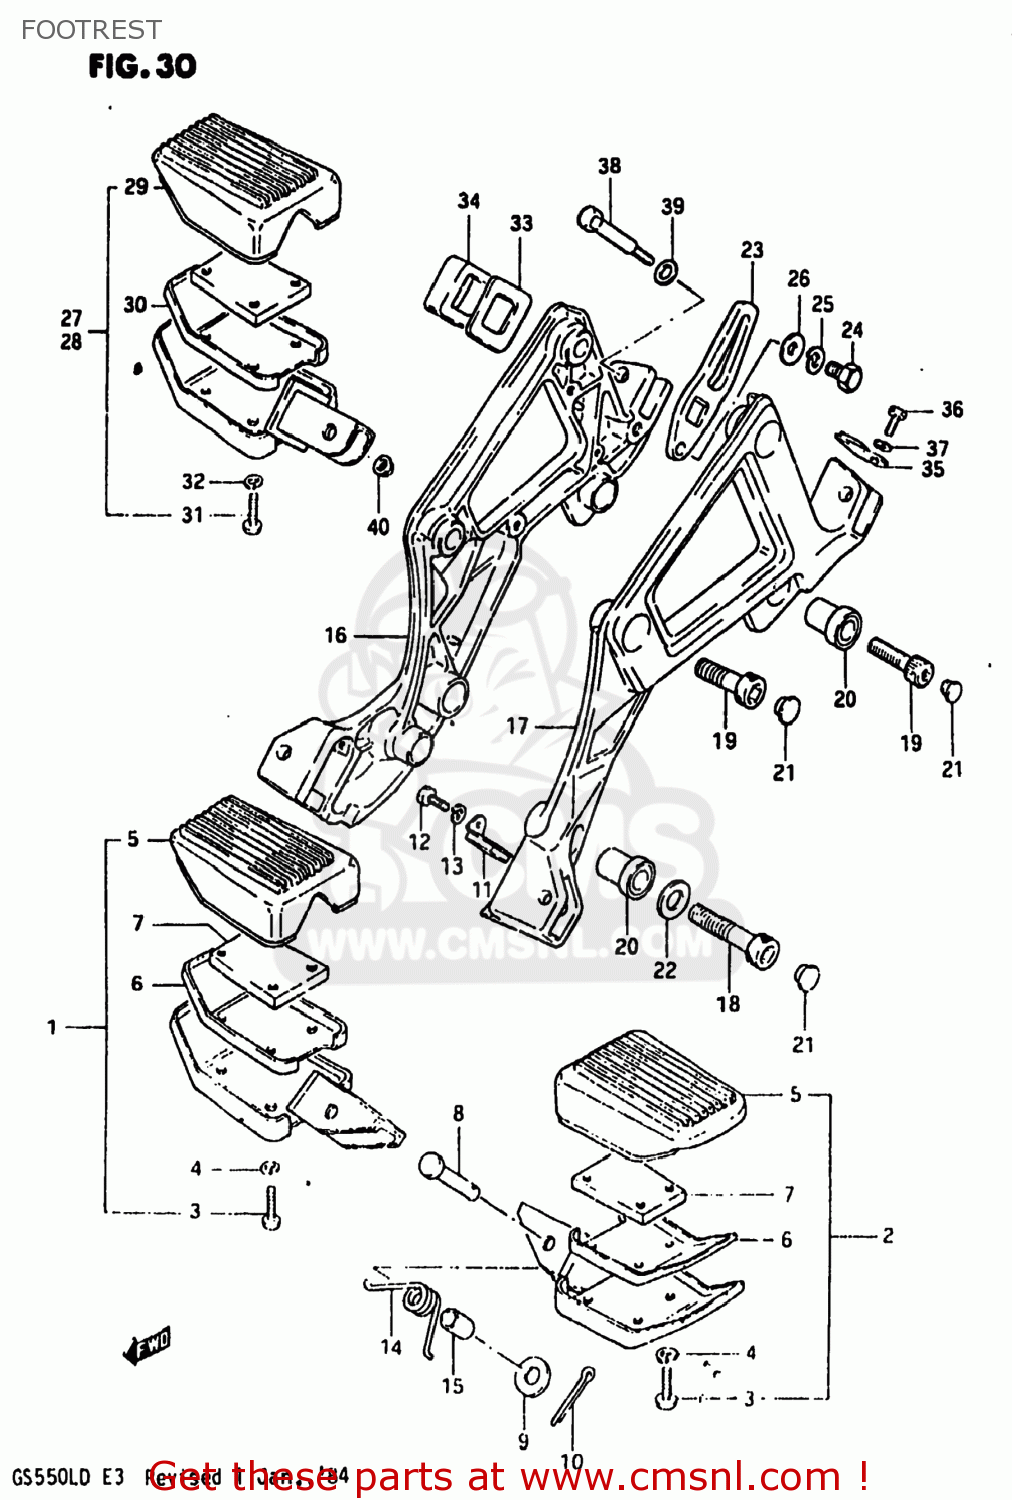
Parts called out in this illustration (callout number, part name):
1	FOOTREST ASSEMBLY,FRONT,RIGHT
2	FOOTREST ASSEMBLY,FRONT,LEFT
3	SCREW
4	LOCK WASHER
5	RUBBER,FRONT FOOTREST
6	PLATE, FOOTREST RUBBER
7	PLATE,FOOTREST RUBBER
8	PIN
9	WASHER
10	PIN 20X20
11	CUSHION,FRONT FOOTREST
12	BOLT 5X10
13	LOCK WASHER
14	SPRING
15	BUSHING
16	BRACKET,MUFFLER,RIGHT
17	BRACKET,MUFFLER,LEFT
18	BOLT
19	BOLT 10X27
20	BUSHING
21	CAP
22	WASHER
23	GUARD,REAR FOOT
24	BOLT
25	LOCK WASHER
26	WASHER
27	FOOTREST ASSEMBLY,REAR
28	FOOTREST ASSEMBLY,PILLION
29	RUBBER,FRONT FOOTREST
31	SCREW
32	LOCK WASHER
33	WASHER,FOOTREST RUBBER
34	CUSHION,REAR FOOTREST
35	CUSHION,REAR FOOTREST
36	BOLT 5X10
37	LOCK WASHER
38	BOLT
39	WASHER
40	NUT
